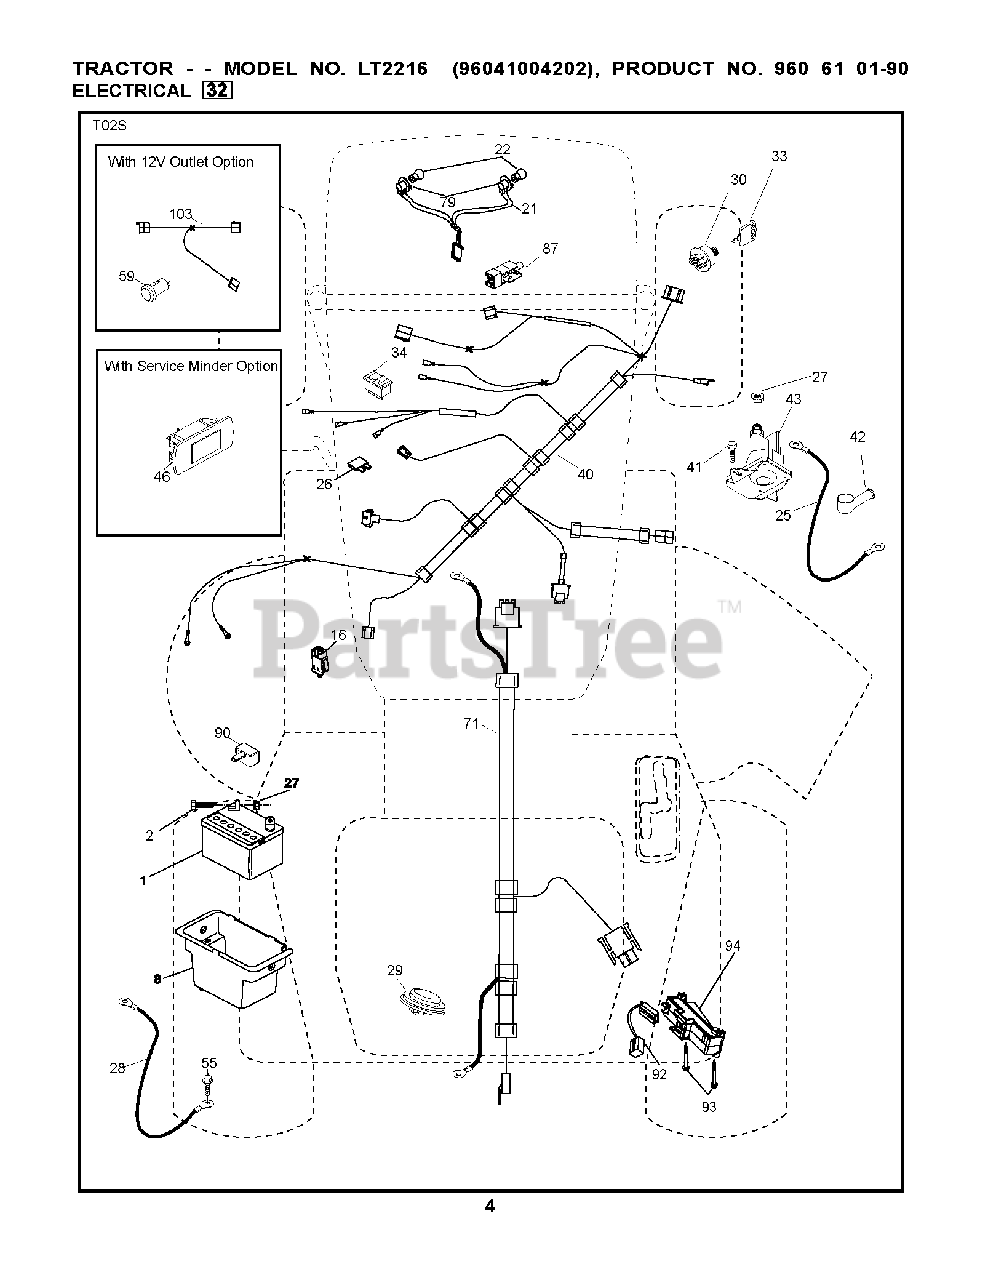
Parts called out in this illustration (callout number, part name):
1	REPL BY 532 12 38-99
8	BOX.BATTERY.MNT.REAR.L
16	SWITCH INTERLOOK PUSH-IN
21	HARNESS ASSY LIGHT
22	LIGHTBULB
25	CABLE.STARTER.6GA.RED.
26	FUSE 20AMP
27	NUT
28	CABLE.BLACK.18"REAR.BA
29	SWITCH.SEAT.DELTA.OPC.
30	SWITCH.IGN.DELTA.W.LGH.ROS
33	KEY.CHAIN.BLISTER.PACK.GEN.INT
34	SWITCH LT
40	HARNESS IGN. DASH
41	SCREW
42	TERMINAL COVER
43	SOLENOID.W/BRASS.PLUNG
55	SCREW 5/16"
71	HARNESS.IGN.CHASS.TEX.REAR.BAT
79	BULB HOLDER ASM.
87	SWITCH.INTRLCK.CLUTCH.
90	COVER, TERMINAL BATTERY
92	HARNESS.PIGTAIL.CONSLE
93	SCREW.PLASTITE
94	MODULE.REVERSE.ROS
